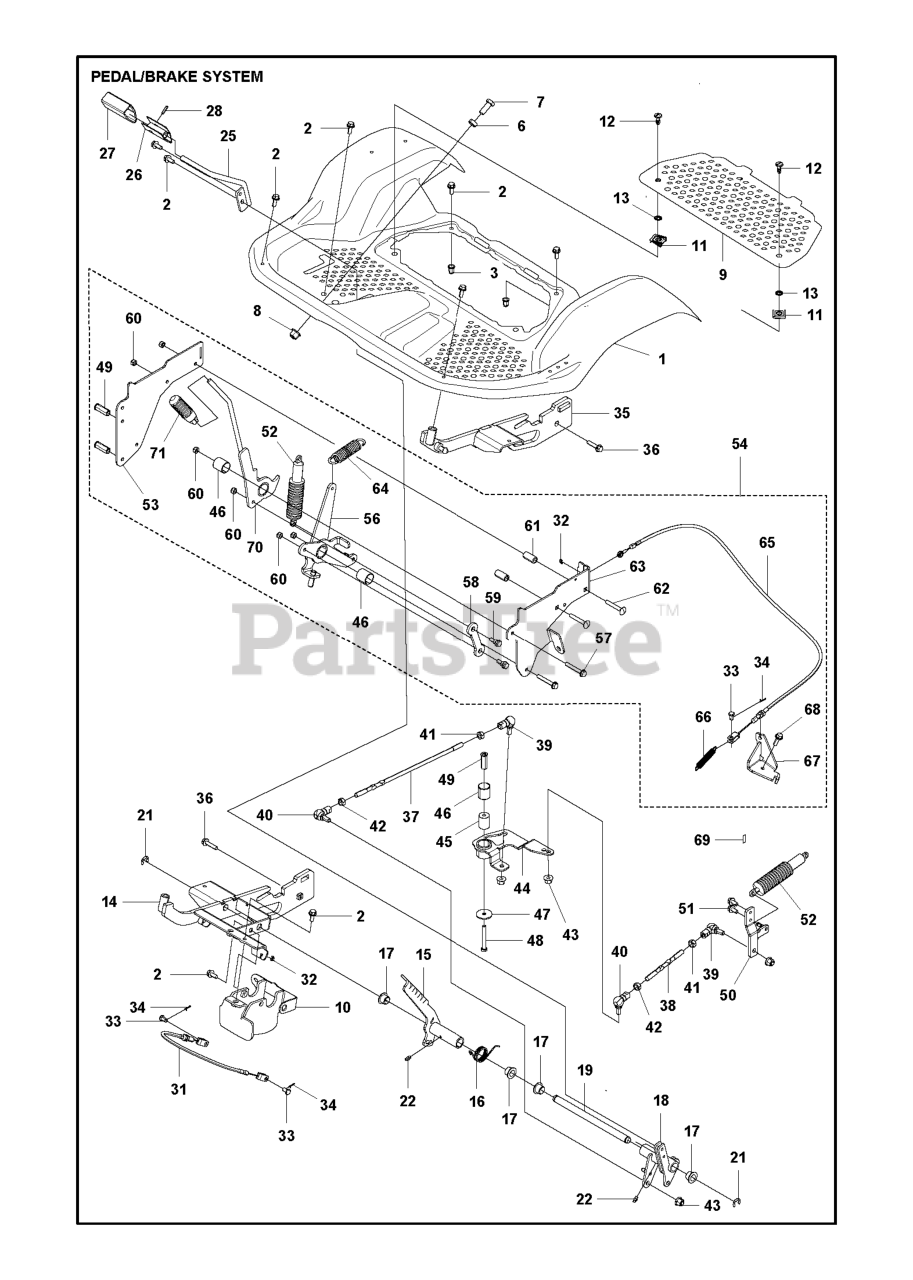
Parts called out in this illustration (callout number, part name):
7	Hex Head Capscrew, M12 X 1.75 X 30 DIN933ZP
17	BUSHING
22	GREASE NIPPLE
27	PEDAL RUBBER
33	Clevis Pin
34	Cotter Pin
36	SCREW EHHFM
46	BUSHING
52	SHOCK ABSORBER
57	SCREW EHHFM
60	LOCKNUT M8
68	BOLT
